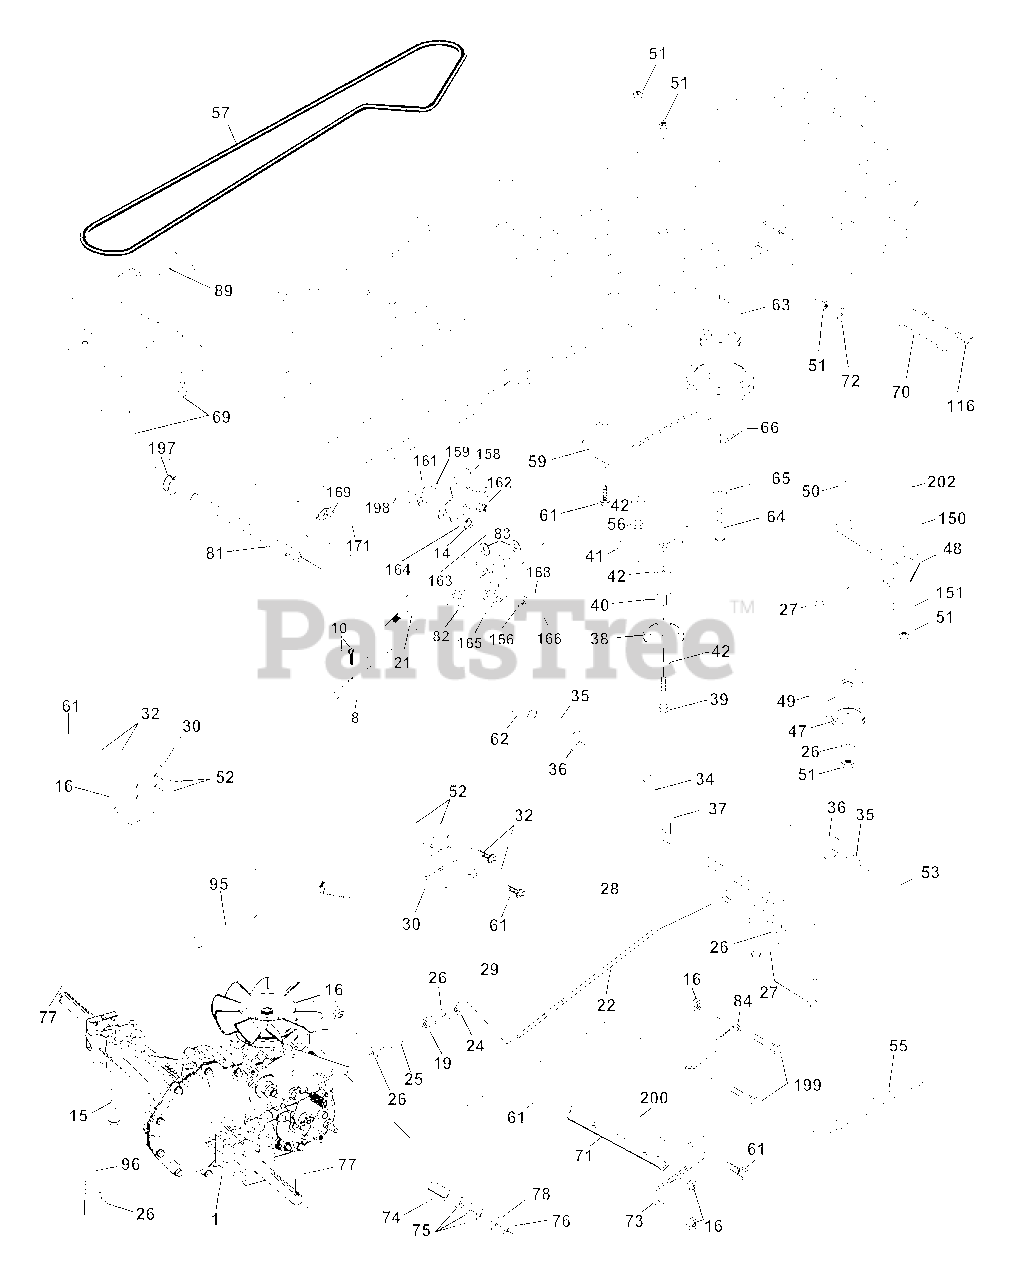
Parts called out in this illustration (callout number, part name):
8	Rod Shift Fender Adjust Yt
10	Pin Cotter 1/8 x 1 CAD
14	Washer Lock Hvy Helical
15	Bolt, Hex FLGHD 5/16-18 Gr. 5
16	Nut Lock Hex W/Ins 5/16-18 Unc P
19	Nut Lock Hex W/Wsh 3/8-16 Unc
21	Knob
22	Rod, Brake Hydro
24	Nut Hex Jam 3/8-16
25	Spring, Brake Rod
26	Washer
27	Pin Cotter 1/8 x 3/4 CAD.
28	Rod, Parking Brake
29	Cap, Parking Brake
30	Bracket, Transaxle
32	Bolt Hex Hd 5/16-18 Unc x 3/4
34	Shaft, Foot Pedal
35	Bearing, Nylon
36	Washer 21/32 x 1x 16 Ga.
37	Pin, Roll 3/16 x 1
38	Pulley, Idler, Flat
39	Bolt Rdhd 3/8-16 Unc x 2-3/4 Gr. 5
40	Spacer, Split
41	Keeper, Belt Retainer
42	Washer 13/32 x 13/16 x 12 Gauge
47	Pulley, Idler, V-Groove
48	Bellcrank Clutch Grnd Drv STL
49	Retainer, Belt
50	Bolt Hex Hd 3/8-16 x 1-1/2
51	Nut Crownlock 3/8-16 UNC
52	Nut Crownlock 5/16-18 UNC
53	Link, Clutch
55	Spring, Return, Clutch
56	Bolt Fin Hex 3/8-16 UNC x 1-1/4
57	V-Belt, Hydro
59	Keeper, Center Span
61	Screw 3/8-16 x 3/4
62	Cover, Pedal
63	Pulley, Engine
64	Bolt, Hex 7/16-20 x 4
65	Washer Lock Hvy. Hlcl Spr 7/16
66	Keeper Belt Engine F-Proof
69	Screw Hex Wsh Hi-Lo 1/4-1/2
70	Guide Belt Engine
71	Strap Torque Lh Hydro
72	Washer 13/32 x 1-1/4 x 12 Gauge
73	Strap Torque Rh Hydro
74	Spacer, Axle
75	Washer 25/32 x 1-1/4 x 16 Gauge
76	E-Ring #5133-75
77	Key, Square
78	Washer 25/32 x 1-5/8 x 16 Gauge
81	Shaft Asm Cross Tapered
82	Spring Torsion T/A
83	Washer 17/32 x 3/4 x 16 Ga.
84	Link Transaxle
89	Console, Shift
95	Control Asm Bypass Hydro
96	Retainer Spring 1" Zinc/Cad
116	Bolt Rdhd Sq. Neck 3/8-16 x 1.25
150	Bushing Bellcrank
151	Washer 13/32 x 2 x 10 Ga.
156	Washer Srrted 5/16 ID X 1 X .125
158	Bracket Shift Mount
159	Hub Tapered Flange Shift LT
161	Bolt Rdhd Sqnk 1/4-20 x 3/4 Gr. 5
162	Nut Crownlock 1/4-20 Unc
163	Bolt Hex Fin 1/4-20 Unc x 1 Gr. 5
164	Washer 5/8 x .281 x 10 Ga.
165	Bracket Pivot Lever
166	Screw 5/16-18 x 5/8
168	Bolt Shoulder 5/16-18 x .561
169	Plate Fastening LT
171	Screw Thdrol 3/8-16 x 1/2 TY-TT
197	Nyliner Snap- In
198	Washer Nyliner
199	Bolt Shoulder 5/16-18 Unc
200	Bolt Rdhd Sqnk 5/16-18 Unc x 1
202	Bolt Carr Sh 3/8-16 x 1-1/2 Gr. 5
